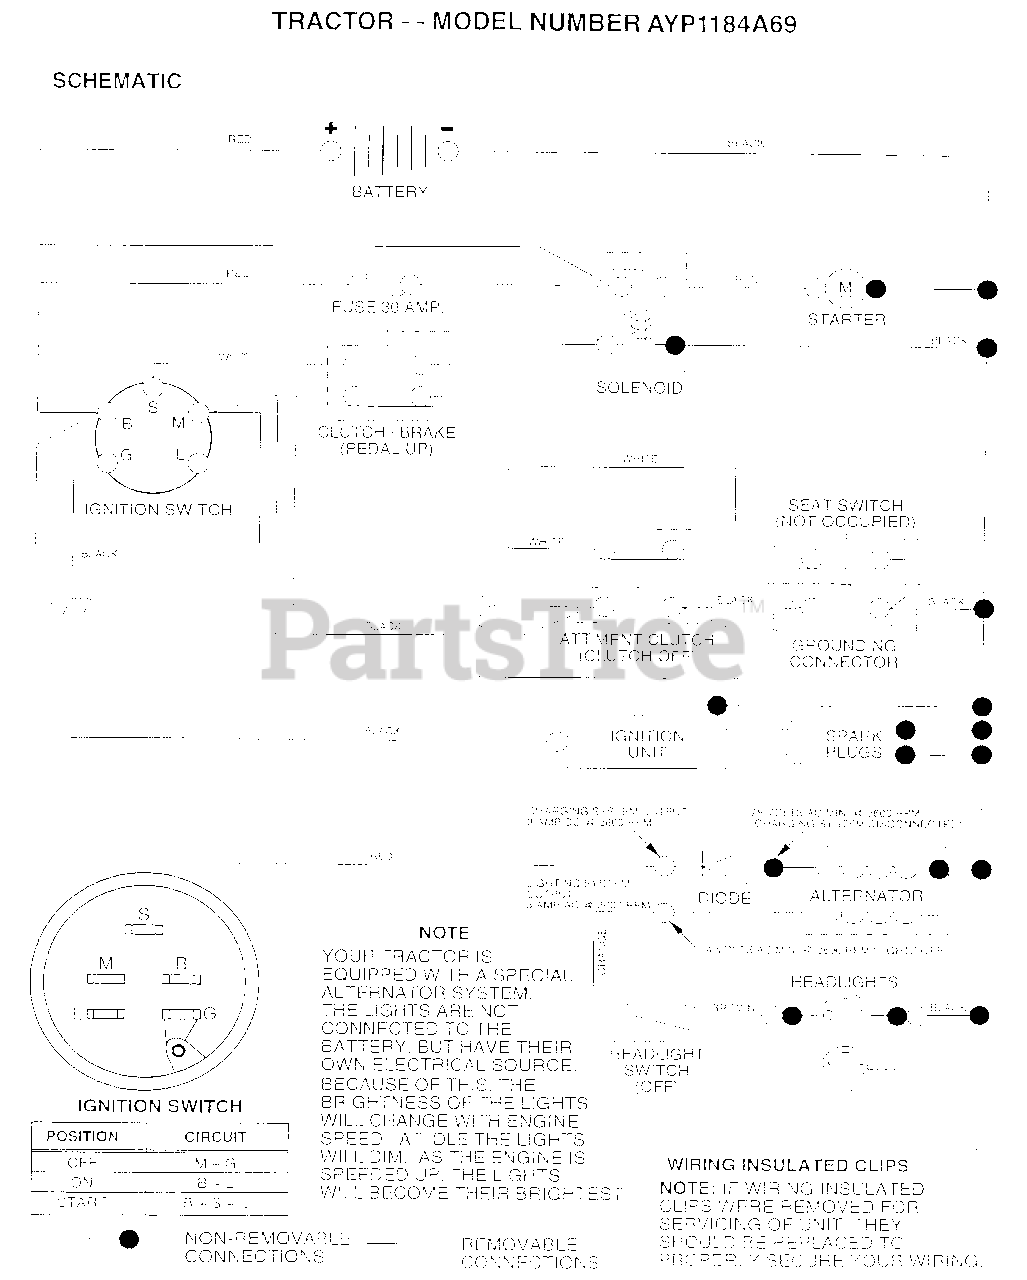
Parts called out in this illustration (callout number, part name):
2	BOLT LT
3	WASHER
4	LOCKWASHER
7	TUBE T
9	HOSE CLAMP T
15	FASTNER.SNAP-IN
20	NUT
21	"HARNESS,LIGHT SOC"
22	HEADLAMP BULB
24	CABLE-BATTERY T
25	CABLE.BTRY.6GA.RD
26	FUSE HYT
28	CABLE T
29	SWITCH SEAT
30	SWITCH IGN 4POS
31	NUT IGNITION
32	COVER KEY SWITCH
33	KEY
35	BRACKET LT
36	SCREW
38	BRACKET SWITCH IN
39	SWITCH INTERLOCKT
40	HARNESS.IGNITION
44	NUT HXKEP 1/4X20
48	ADAPTER AMMETER
52	PROTECTION LOOP
70	HARNESS.ENG.LT.
471	BOLT HXHD FIN
